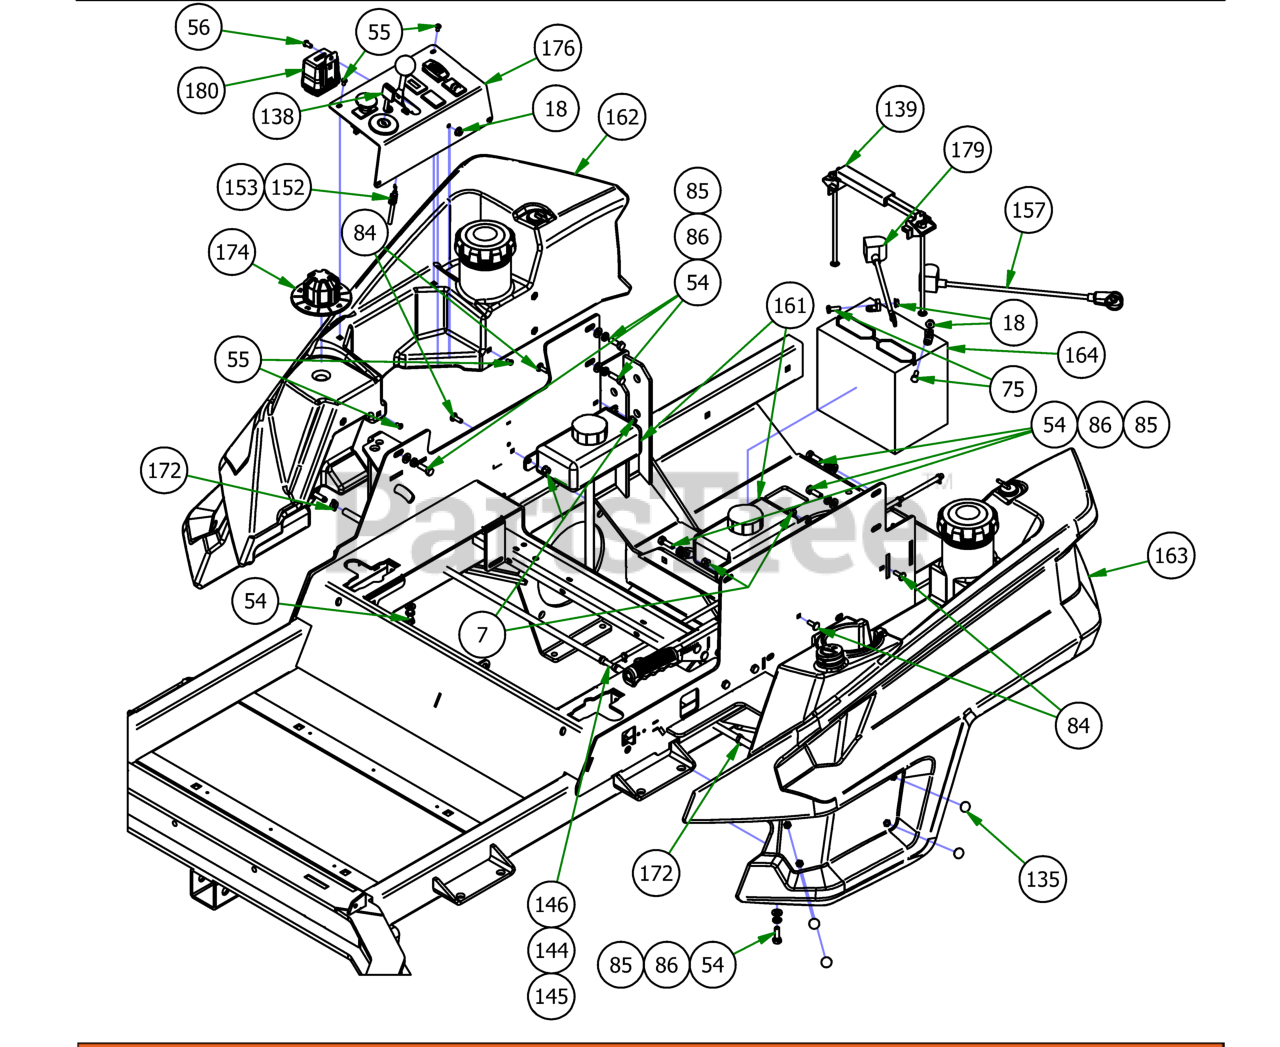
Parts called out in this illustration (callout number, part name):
7	1/4-20 Nylon Insert flange Nut
18	1/4-20 Hex Flange Nuts Zinc w/Serrations
54	5/16" x 1" Bolt
55	10-32 x 3/8" Button Socket Head Bolt
56	1/4" x 1/2" BS C/S 18-8 SS
75	1/4" x 3/4" Hex Bolt
84	1/4" x 3/4" Carriage Bolt
85	5/16" Flat Washer
86	5/16" Lock Washer
135	3/16 x .48 Christmas Tree Nylon Black
138	Ignition Key
139	Hold Down Assembly
144	2019 Rebel Rogue Renegade Fuel Line for Vanguard & Yamaha
145	2019 Rebel Rogue Renegade Fuel Line for Kohler
146	2019 Rebel Rogue Renegade Fuel Line for Kawasaki
152	Outlaw Throttle Cable
153	Throttle Cable for 36Hp Vanguard & FX1000 Kawasaki
157	14" Red Battery Cable-Base Outlaw
161	2019 Rebel Hydro Tank Assembly
162	2019 Right Rebel, Rogue, Renagade Fuel Tank (GAS)
163	2019 Left Rebel, Rogue, Renegade Fuel Tank (GAS)
169	2019 Rebel Frame - Powdercoated
172	2 EAR CLAMP 12.5mm-15mm
174	2019 Rigid Deck Dial 1.5 to 5.5
176	Rebel/Rogue Control Panel Assy
179	Starter Cable
180	2019 Wiring Harness-Rebel/Rogue
